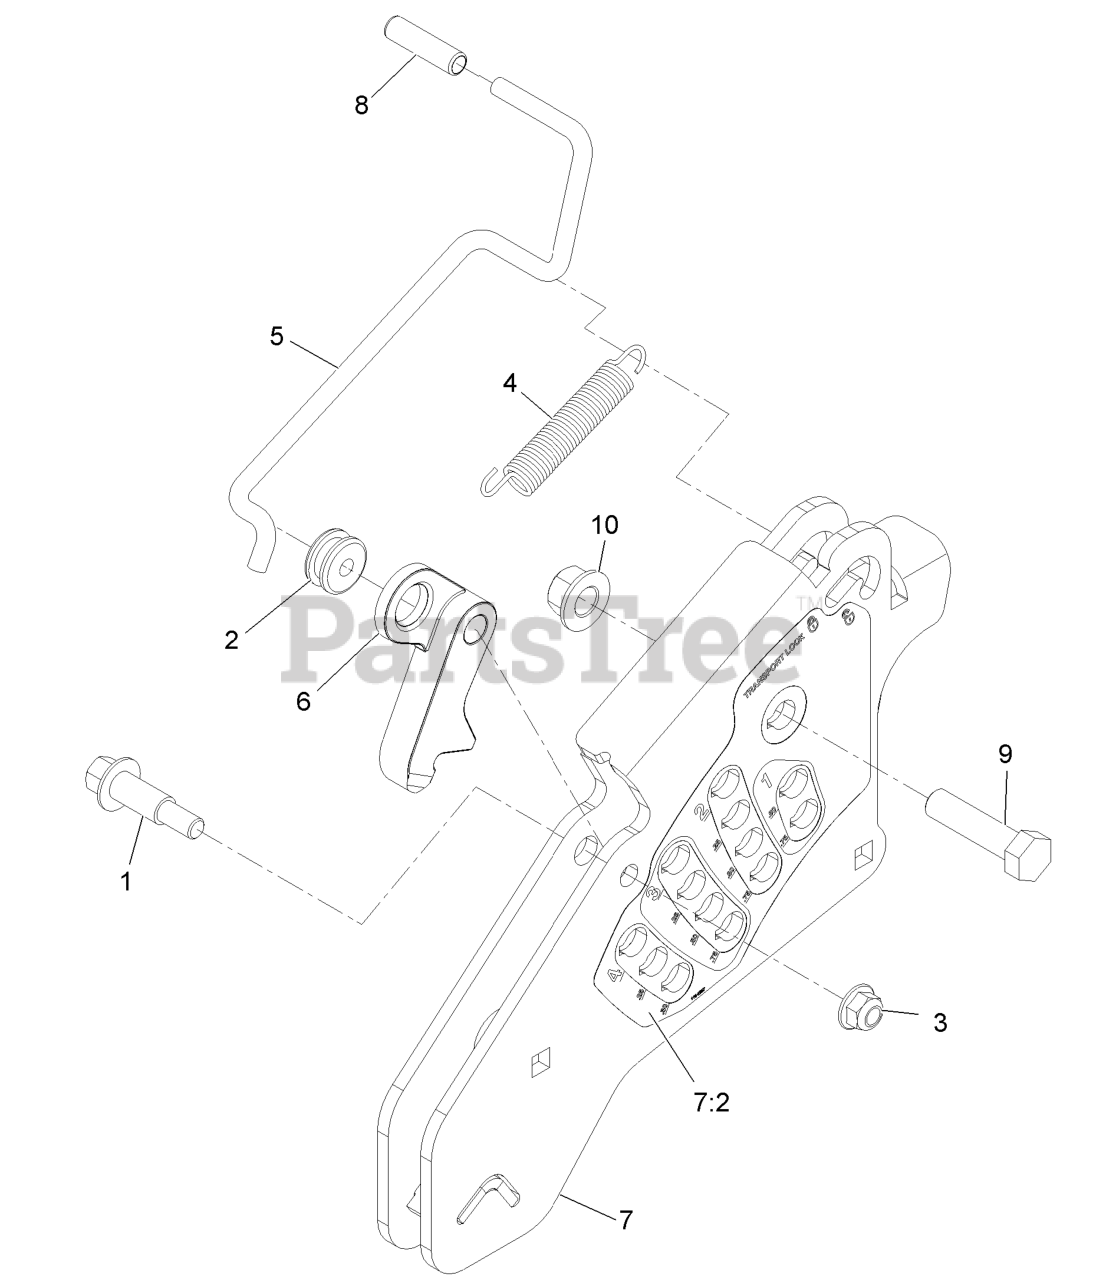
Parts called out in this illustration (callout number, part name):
1	BOLT-SHOULDER
2	GROMMET
3	NUT-HF, NI
4	SPRING-EXTENSION
5	ROD-LOCK, TRANSPORT
6	PAWL-TRANSPORT, HOC
7	HOC PLATE ASM
7:2	DECAL-HOC
8	GRIP-LEVER
9	SCREW-HH
10	Nut-Lock 1/2-13
